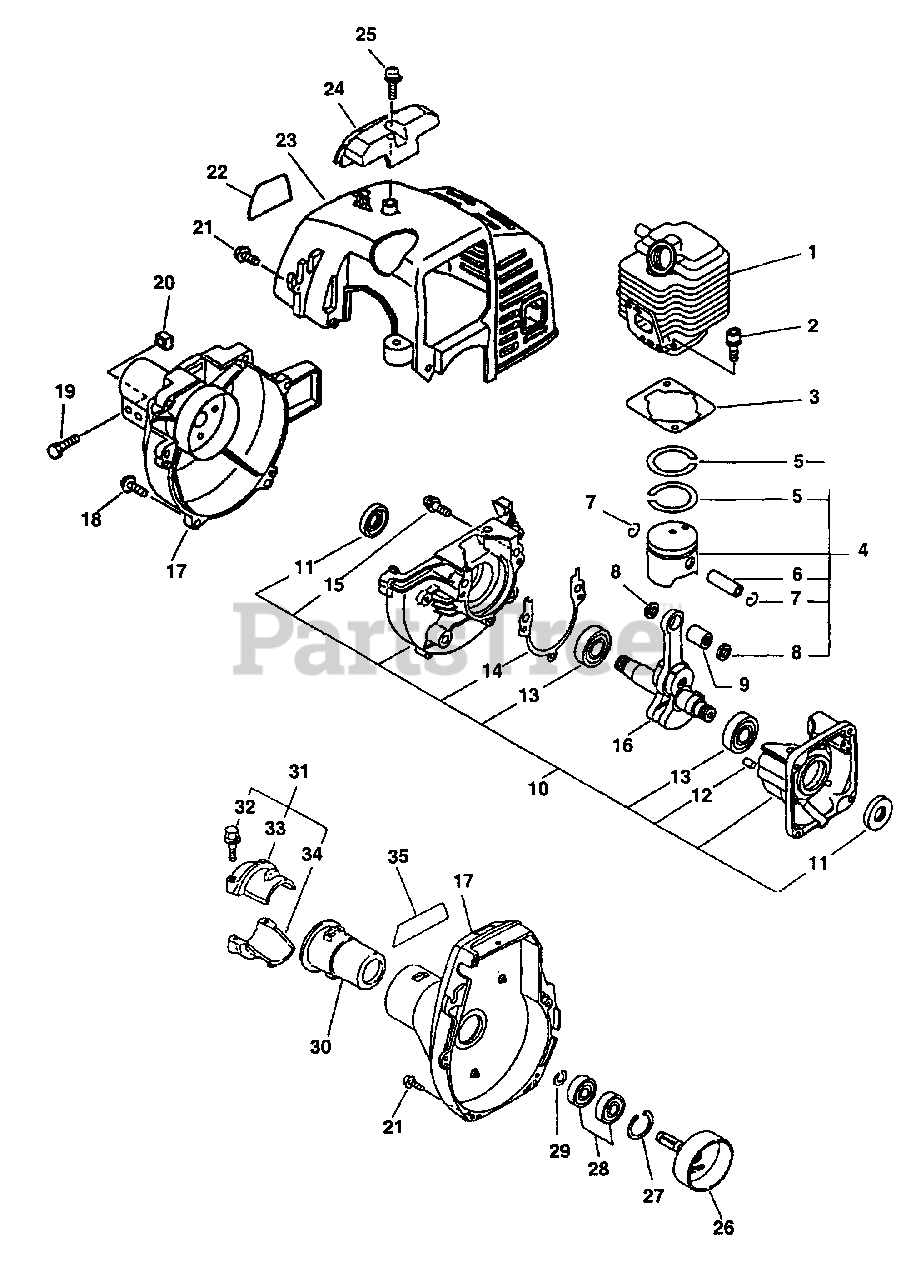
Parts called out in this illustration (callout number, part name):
1	CYLINDER
2	BOLT 5×22
3	GASKET, CYLINDER
4	PISTON KIT
5	RING, PISTON
6	PIN, PISTON 8
7	RING, SNAP
8	WASHER, THRUST
9	BEARING, NEEDLE
10	CRANKCASE KIT
11	SEAL, OIL 12
12	PIN, LOCATING 4
13	BEARING, BALL - 6201 C3
14	GASKET, CRANKCASE
15	BOLT 5×28
16	CRANKSHAFT ASSY
17	FAN CASE ASSY
17	COVER ASSY, FAN
18	SCREW 4×18
19	BOLT 5×28
20	NUT M5
21	BOLT 4×16
22	LABEL - MODEL
23	COVER, ENGINE - GRAY
23	COVER, ENGINE
24	GUARD, TOP - GRAY
24	GUARD, TOP
25	SCREW 5×16
26	DRUM, CLUTCH
27	RING, SNAP 28
28	BEARING, BALL 6001
29	RING, RETAINING - 12
30	CUSHION
31	HOLDER KIT
32	BOLT - 5×25
33	HOLDER, MAIN PIPE - UPPER
34	HOLDER
35	LABEL, GT-2400
